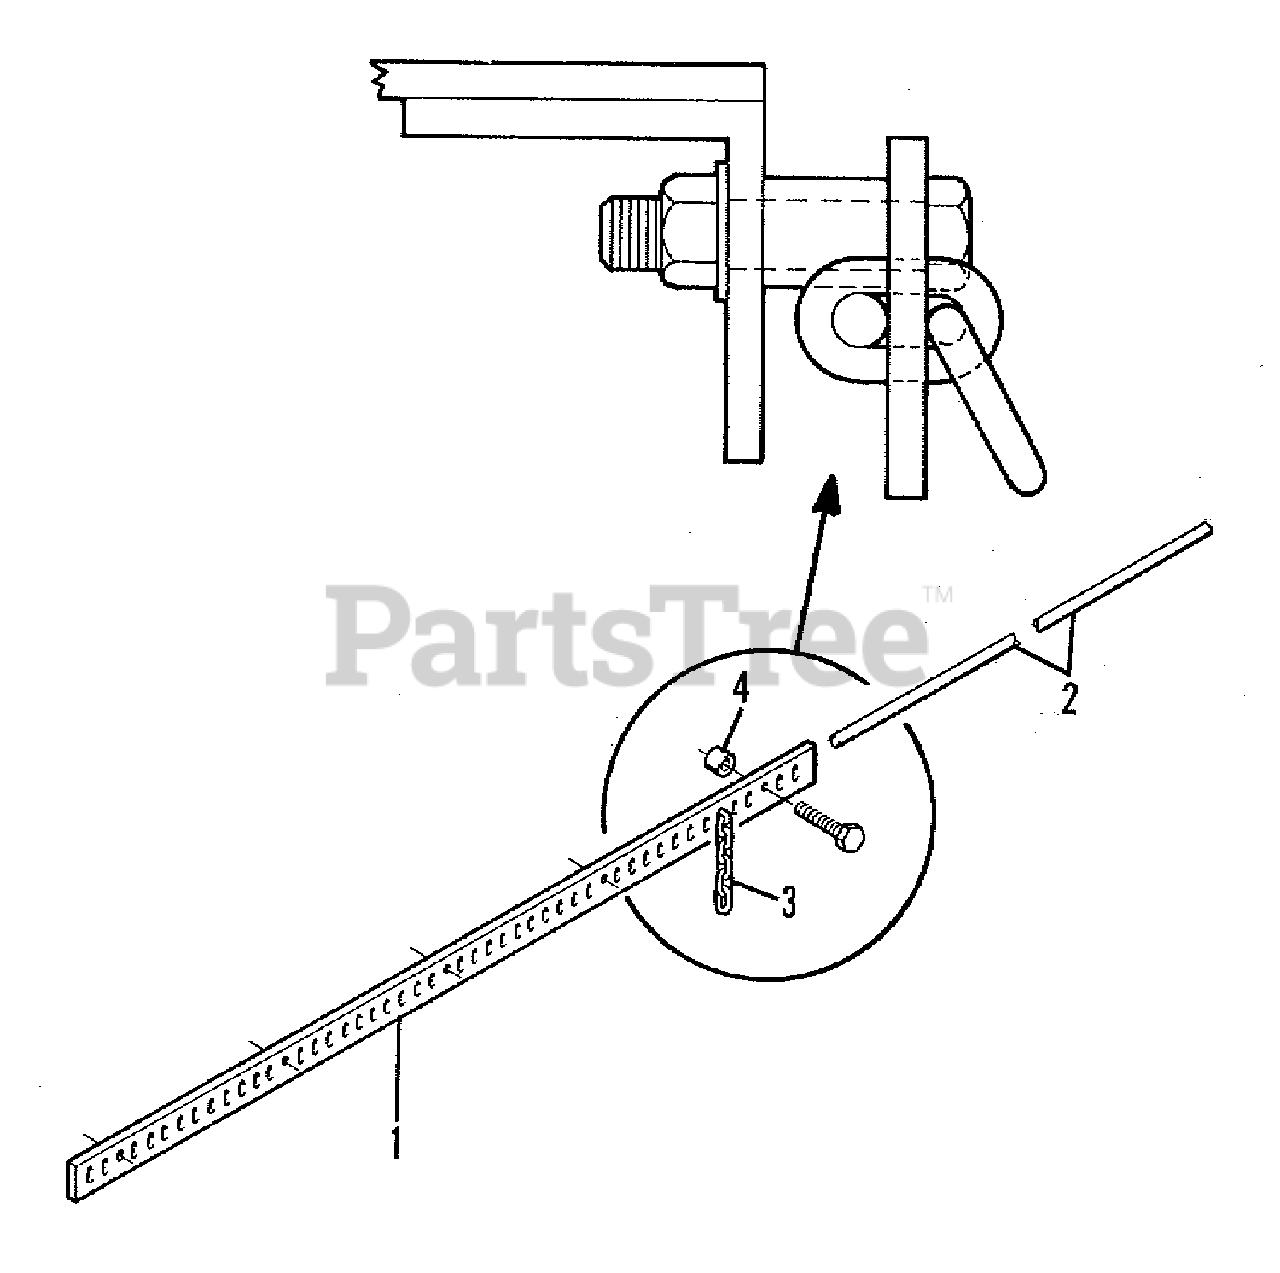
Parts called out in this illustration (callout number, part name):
1	BAR, Chain, Front
2	ROD, Chain (166" Long)
4	SPACER, Bar
4	CAPSCREW, 1/2NC x 2-1/4
4	LOCKWASHER, 1/2
